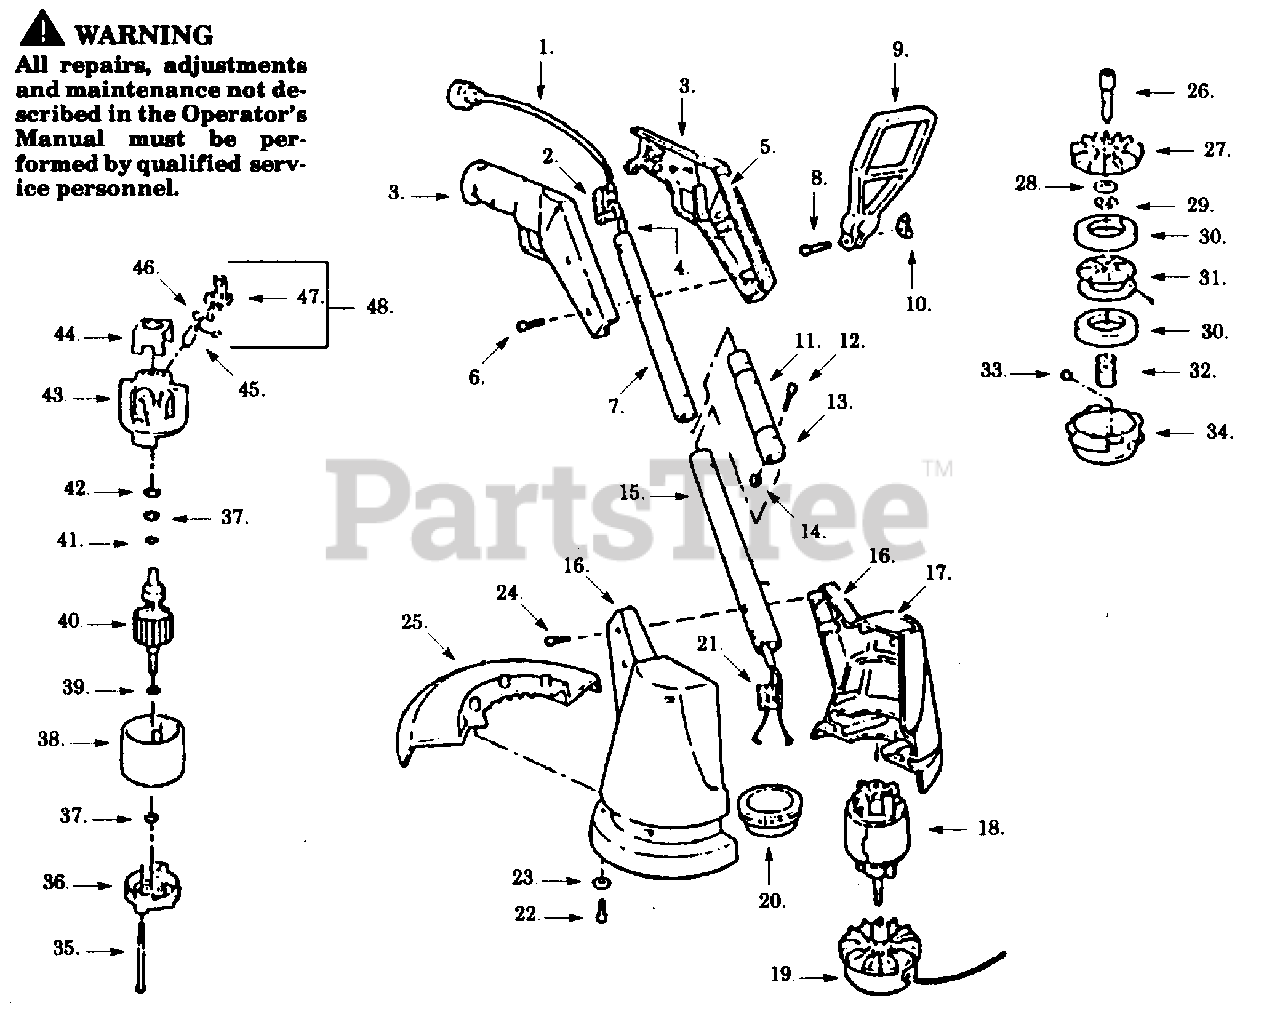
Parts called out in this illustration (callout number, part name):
1	Power Cord
2	Trigger Switch
3	Handle Set
5	Handle Label
7	Upper Tube
9	Assist Handle Ass'y.
10	Wing Nut
11	Warning Label (Not a serviceable part)
13	Outer Tube
14	Stop Nut
15	Lower Tube
16	Housing Set
17	Housing Label
18	Motor Ass'y.
19	Cutting Head Ass'y.
20	Air Baffle
21	P.C. Bridge
25	Guard & Blade Ass'y.
26	Drive Adapter
27	Rear Plate
29	Retaining Ring
30	Foam Pad
31	Spool & Line
34	Hub Ass'y.
36	Endbell Ass'y. (Drive)
38	Field Ass'y.
39	Retaining Ring
40	Armature Ass'y.
41	Retaining Ring
43	Endbell Ass'y. (Brush)
44	Insulator
45	Carbon Brush
46	Brush Spring
47	Brush Holder
48	Brush Kit (Incl. 45,46,47)
